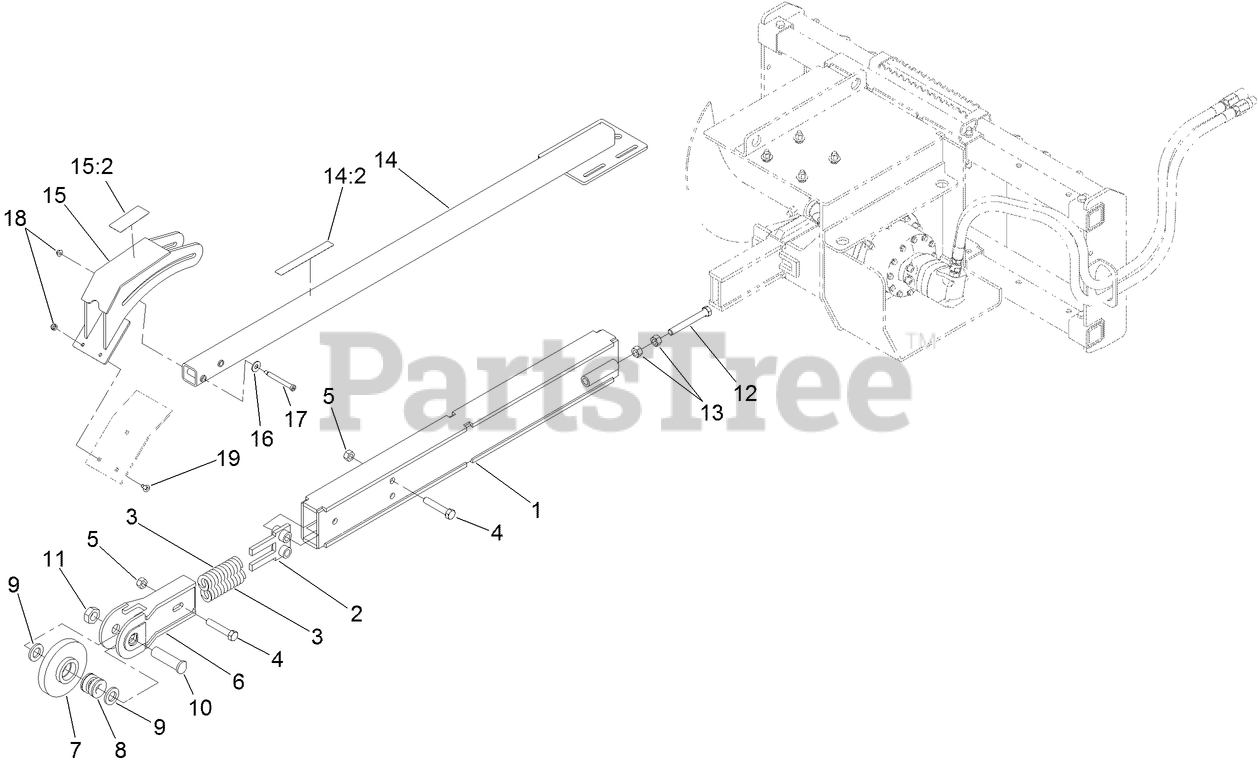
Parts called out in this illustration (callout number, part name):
1	ARM-TRENCHER
2	GUIDE-SPRING, TRENCHER
3	SPRING-COMPRESSION
4	SCREW-HH
5	NUT-LOCK
6	MOUNT-WHEEL, IDLER
7	WHEEL-IDLER
8	BEARING
9	SPACER
10	SHAFT-IDLER
11	NUT-LOCK, NI
13	NUT-HEX
14	60 INCH CRUMBER ARM ASM
14:2	DECAL-DANGER
15	CRUMBER ASM
15:2	DECAL-DANGER
16	WASHER-FLAT
18	NUT-HF, NI
19	SCREW-HH
